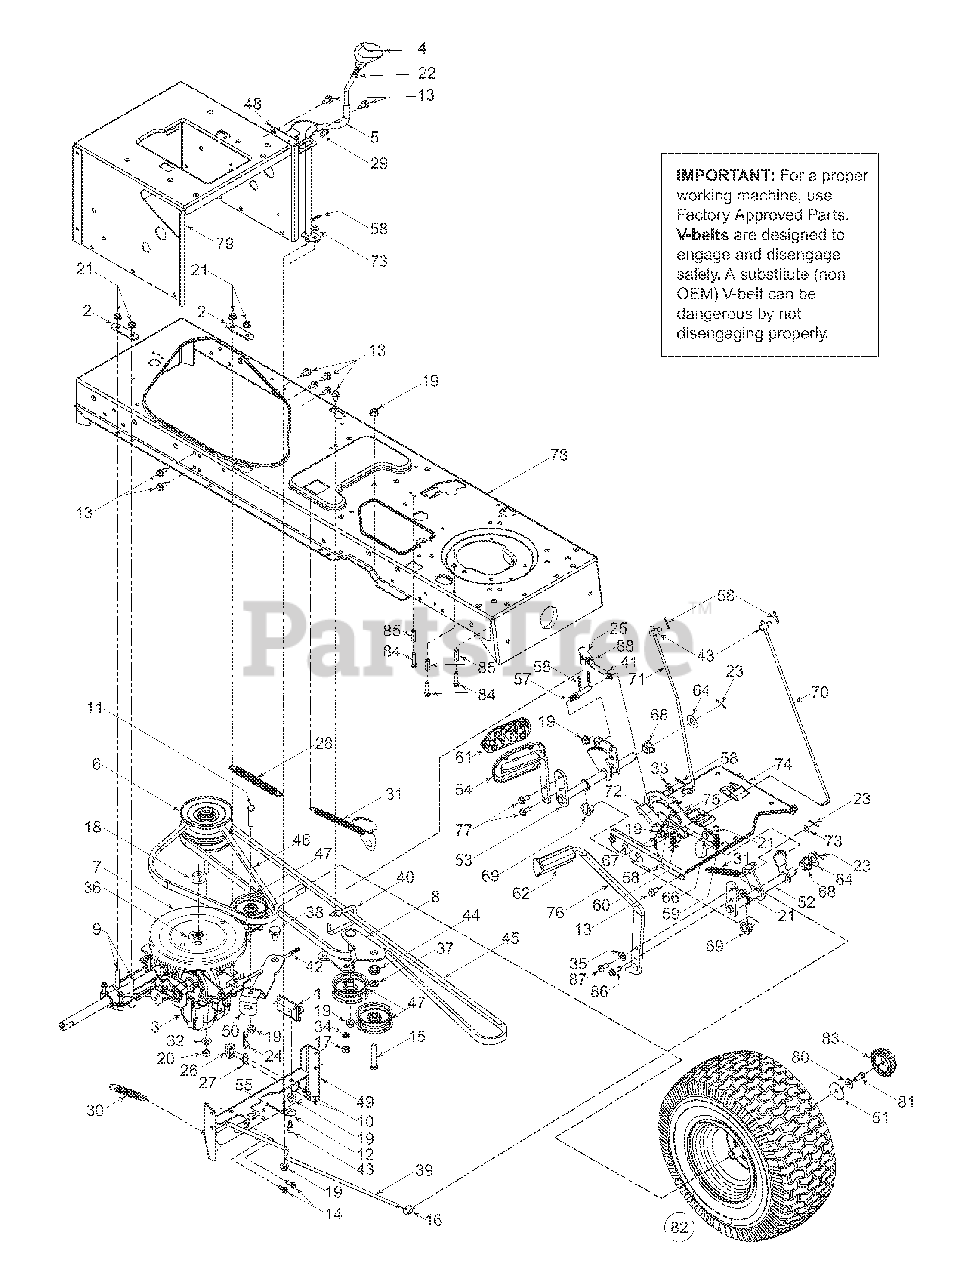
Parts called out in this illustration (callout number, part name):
3	Single-speed Transmission Assembly
4	Shifter Knob
5	Shift Lever
6	Variable-speed Pulley Assembly
7	Transmission Pulley, 8.5 x .5-36
8	Double-idler Bracket
9	Hex Cap Screw, 5/16-18 x 2.75
10	Self-tapping Screw, #8-18 x .5
11	Hex Cap Screw, 3/8-16 x 1.75
12	Flat Washer, .51 x 1.0 x .060
13	Self-tapping Screw, 5/16-18 x .75
14	Self-tapping Screw, 1/4-20 x .75
15	Hex Cap Screw, 3/8-16 x 2.25
16	Ferrule, 5/16-18
17	Hex Nut, 3/8-24
18	Hex Nut, 7/16-20
19	Flange Lock Nut, 3/8-16
20	Hex Nut, 3/8-16
21	Flange Lock Nut, 5/16-18
22	Jam Nut, 3/8-16
23	Cotter Pin
24	Cotter Pin
25	Ball Joint
26	Short Spring Switch
27	Insulator Nut Plate
28	Extension Spring, .62 Dia. x 6.12
29	Compression Spring Clip
30	Extension Spring, .59 OD x 4
31	Extension Spring, .50 Dia. x 6.37
32	Bell Washer, .401 x .87 x .063
33	Flat Washer, .385 x .87 x .09
34	Lock Washer, 3/8
35	Flat Washer, .344 x .750 x .120
36	Pulley Hub
37	Flat Washer, .407 x .812 x .135
38	Shoulder Screw, .625 x .217
39	Brake Rod
40	Belt Guard
41	Idler Adjustment Rod, 3/8
42	Shift Rod
43	Adjustment Ferrule, 1/4-20 x 1.0
44	Shoulder Spacer, .38 ID
45	Lower Drive Belt
46	Upper Drive Belt
47	Flat Idler, 2.75 OD
48	Speed Control Rod Bracket
51	Flat Washer, .350 x 1.59 x .062
54	Drive Pedal Assembly
55	Cotter Pin, 1/8 x 1.25
57	Pin, 3/8-16 x 2.43
58	Cotter Pin
59	Compression Spring, .34 OD x 1.0
60	Extension Spring, .50 OD x 1.41
61	Drive Pedal Pad
62	Brake Pedal Pad
64	Flat Washer, .64 x 1.24 x .06
66	Shoulder Screw, .437 x 1.62
67	Shoulder Screw, .5 x .434
68	Hex Flange Bearing
69	Split Hex Flange Bearing
70	Cruise Control Rod
71	Brake Lock Control Rod
72	Cruise Latch
73	Flat Washer, .344 x .688 x .065
75	Drive Lockout Bracket
81	Hex Cap Screw, 5/16-24 x .75
83	Deluxe Hub Cap
84	Self-tapping Screw, 1/4-20 x 1.25
85	Spacer
86	Self-tapping Screw, 5/16-18 x .875
87	Screw, 5/16-18 x .75
88	Hex Nut, 3/8-24
